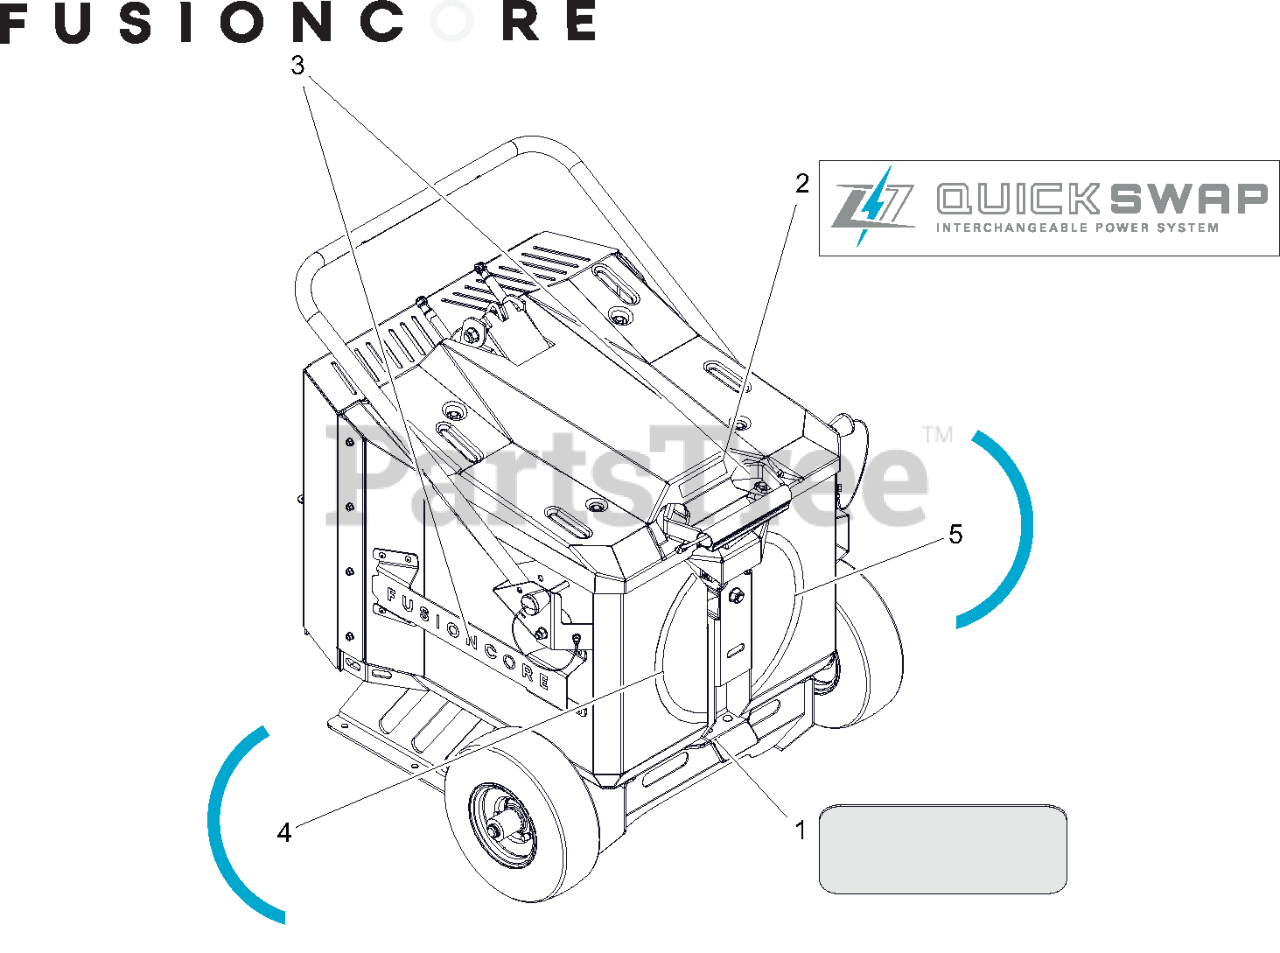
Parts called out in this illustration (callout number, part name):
1	GRIP, PEDAL 1.50 X 3.00
2	DECAL, QUICK SWAP - HATCH
3	DECAL, FUSIONCORE
4	DECAL, FUSION -LH
5	DECAL, FUSION -RH
